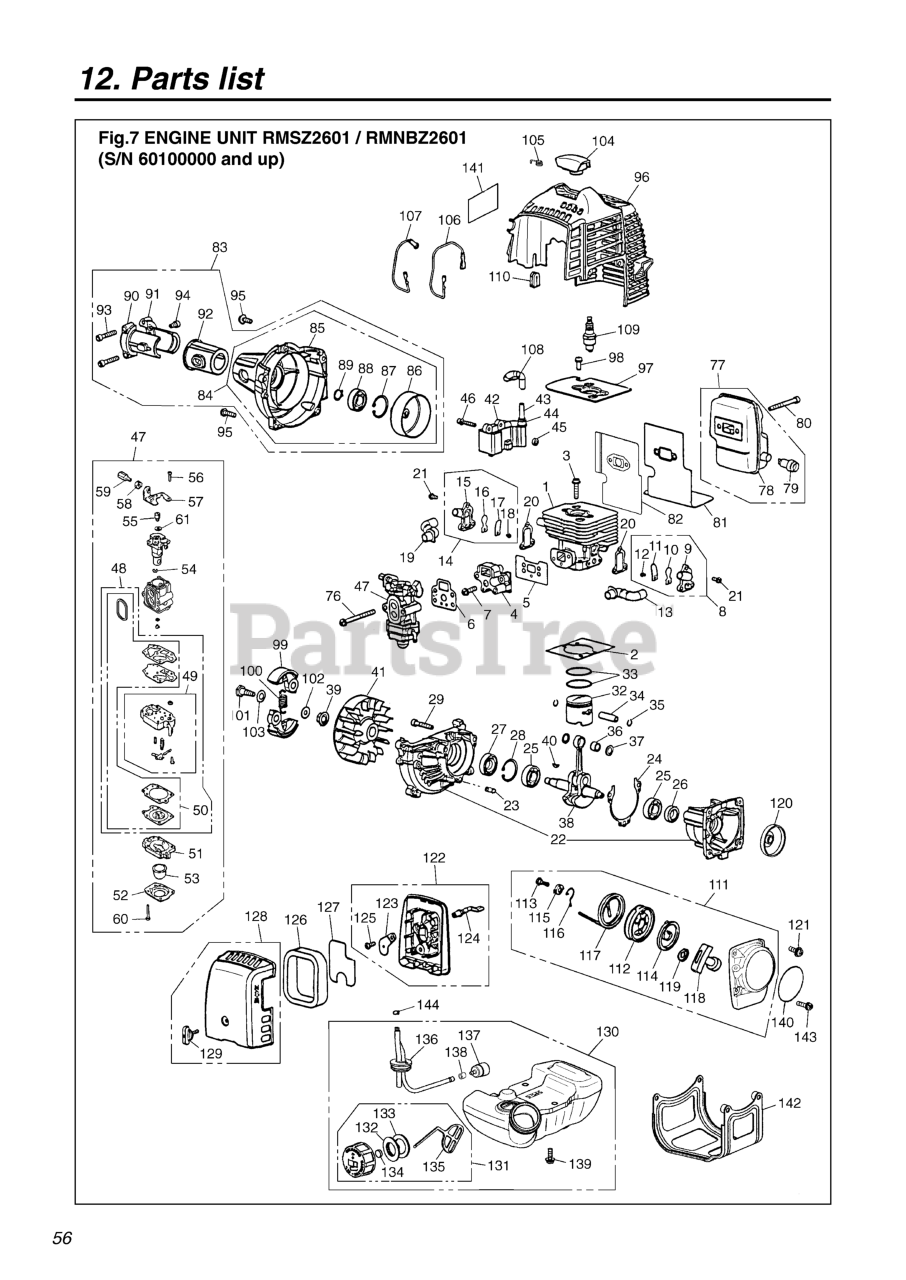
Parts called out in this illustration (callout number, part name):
1	CYLINDER
2	GASKET
3	BOLT
4	INSULATOR
5	GASKET, INSULATOR
6	GASKET, CARBURETOR
7	BOLT (RPLS 2850-14220)
8	REEDVALVE ASSY S
9	VALVECASE
10	REEDVALVE
11	STOPPER
12	SCREW, M3 x 8
13	PIPE, AIR S
14	REEDVALVE ASSY F
15	VALVECASE
16	REEDVALVE
17	STOPPER
18	SCREW, M3 x 8
19	PIPE, AIR F
20	GASKET, VALVE
21	SCREW
22	CRANKCASE-C
23	PIN
24	GASKET
25	BEARING
26	SEAL
27	SEAL, OIL (RPLS 1140-21220)
28	RING, SNAP, M28 x 1.2
29	BOLT
32	PISTON
33	RING, PISTON
34	PIN
35	RING, SNAP (RPLS 1101-41320)
36	BEARING (RPLS 1140-41330)
37	WASHER
38	CRANKSHAFT COMP
40	KEY
41	ROTOR
42	COIL-A
43	CORD
44	CAP
45	SPACER (RPLS -71260)
46	BOLT TORX
47	CARBURETOR
48	REBUILD KIT
49	BODY, PUMP
50	KIT, GASKET (REPLACES-06020)
51	BODY, PURGE
52	COVER, PUMP
53	PUMP, PRIMING
54	RING
55	SWIVEL
56	SCREW
58	NUT, CABLE ADJUSTER
59	SCREW, CABLE ADJUSTER
60	SCREW
61	WASHER
76	BOLT
77	MUFFLER-A
79	ARRESTER
80	BOLT
81	GASKET
82	PLATE, MUFFLER
83	COVER ASSY
84	COVER COMP. (REPLACES -31101)
85	COVER, FAN (REPLACES -31110)
86	DRUM (REPLACES 4810-31122)
87	RING, SNAP, M28 x 1.2
88	BEARING
89	RING, SNAP (RPLS 3130-13270)
90	BRACKET (A) (RPLS -31210)
91	BRACKET (B) (REPLACES -31220)
92	CUSHION
93	BOLT
94	BOLT
95	BOLT, TORX
96	COVER, ENGINE
97	PLATE
98	BOLT
99	SHOE
100	SPRING
101	BOLT
102	WASHER, FLAT (USE 182303)
103	WASHER (RPLS -51241)
104	CAP (RPLS 4810-72110)
105	SPRING
106	CORD (BLACK)
107	CORD, EARTH (RED)
108	TUBE
110	GROMMET
111	RECOIL ASSEMBLY
112	REEL
113	SCREW
114	SPRING, SPIRAL
115	COLLAR
116	ARM
117	ROPE (REPLACES 4500-75160)
118	KNOB (RPLS -75420)
119	PLATE, STOPPER
120	PULLEY
121	BOLT
122	BODY ASSEMBLY
123	PLATE, CHOKE
124	LEVER, CHOKE
125	SCREW
126	ELEMENT
127	SCREEN
128	COVER ASSEMBLY
129	KNOB (RPLS -82220)
130	TANK ASSY
131	CAP ASSY (RPLS -85201)
132	HOLDER (REPLACES -85230)
133	PACKING
134	FILTER
135	STOPPER
136	PIPE COMPLETE
137	FILTER ASSY
138	CLIP (REPLACES 2841-31280)
139	BOLT
140	LABEL, RECOIL
141	LABEL, COVER
142	GUARD (RPLS 4810-31911)
143	BOLT
144	CLIP
